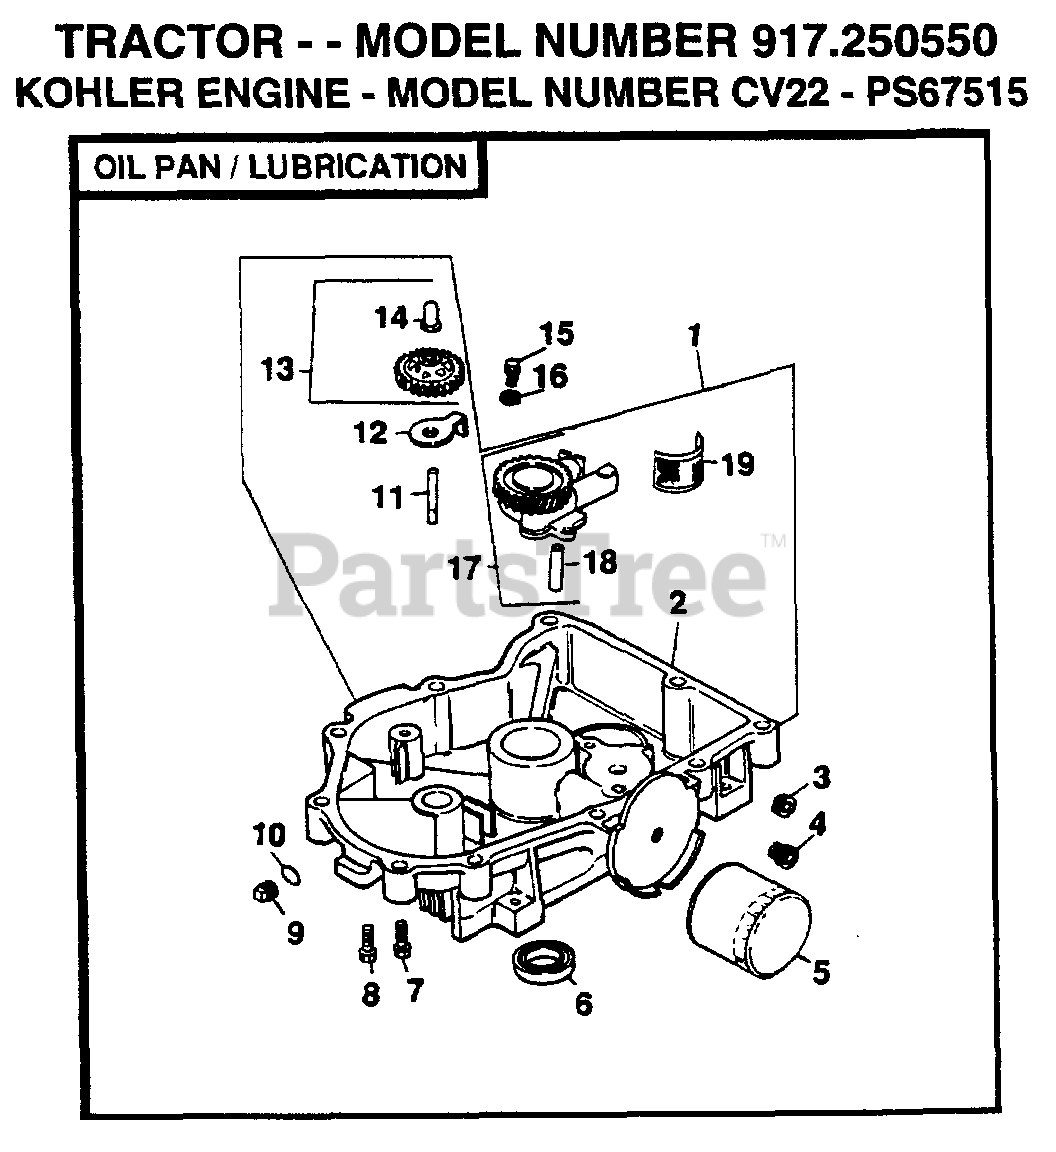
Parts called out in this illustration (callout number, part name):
3	NIPPLE, OIL FILTER
12	GOVERNOR GEAR ASSY
16	OIL PUMP ASSY
